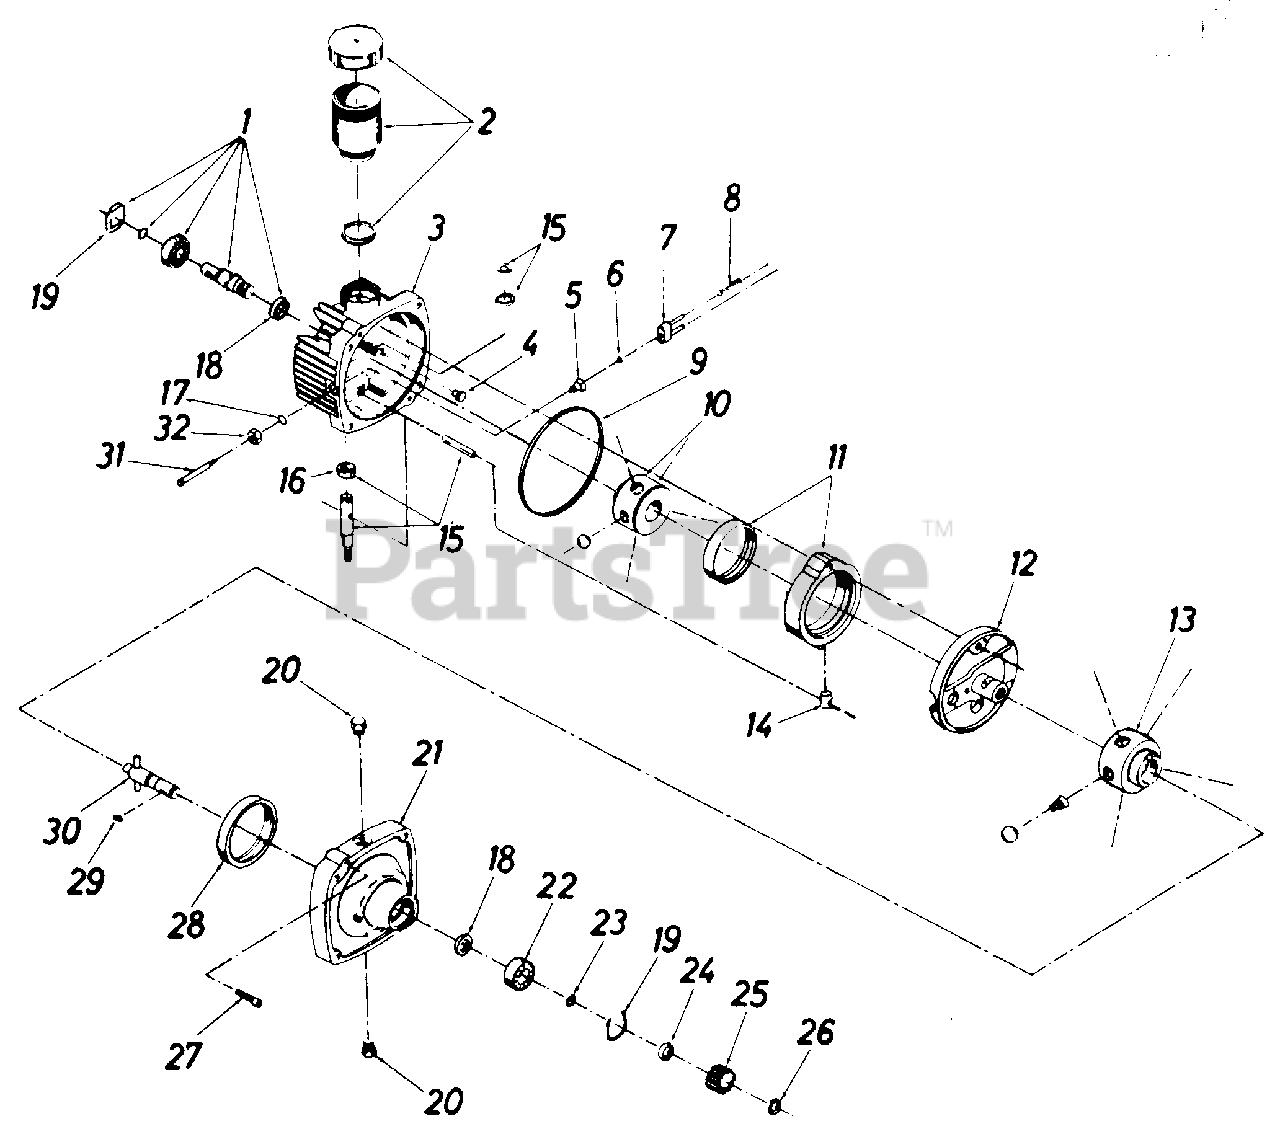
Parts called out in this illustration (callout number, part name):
1	Kit-Input Shaft
2	Kit-Reservoir
3	Kit Cover
5	O-Ring Fitting Guide Subassembly
7	Bracket-Pins Sub-assembly
8	Valve Spring
9	Square Cut Seal Ring
10	Pump Rotor-Ball Sub-assembly
11	Cam Ring Subassembly
12	Pintle Subassembly
13	Motor Rotor-Ball Sub-assembly
14	Cam Ring Insert
15	Kit-Control Shaft
16	Oil Seal
17	O-Ring.013
19	Retaining Ring
20	O-Ring Plug Subassembly
22	Ball Bearing
23	Snap Ring
25	Drive Gear (12 Teeth)
26	External Retaining Ring
27	Socket Hd. Scr. 5/16-18 x 1.25" Lg.
28	Motor Race
29	Woodruff Key #3
30	Output Shaft Subassembly
31	Dump Valve Shaft
32	Nut-Gasket Subassembly
